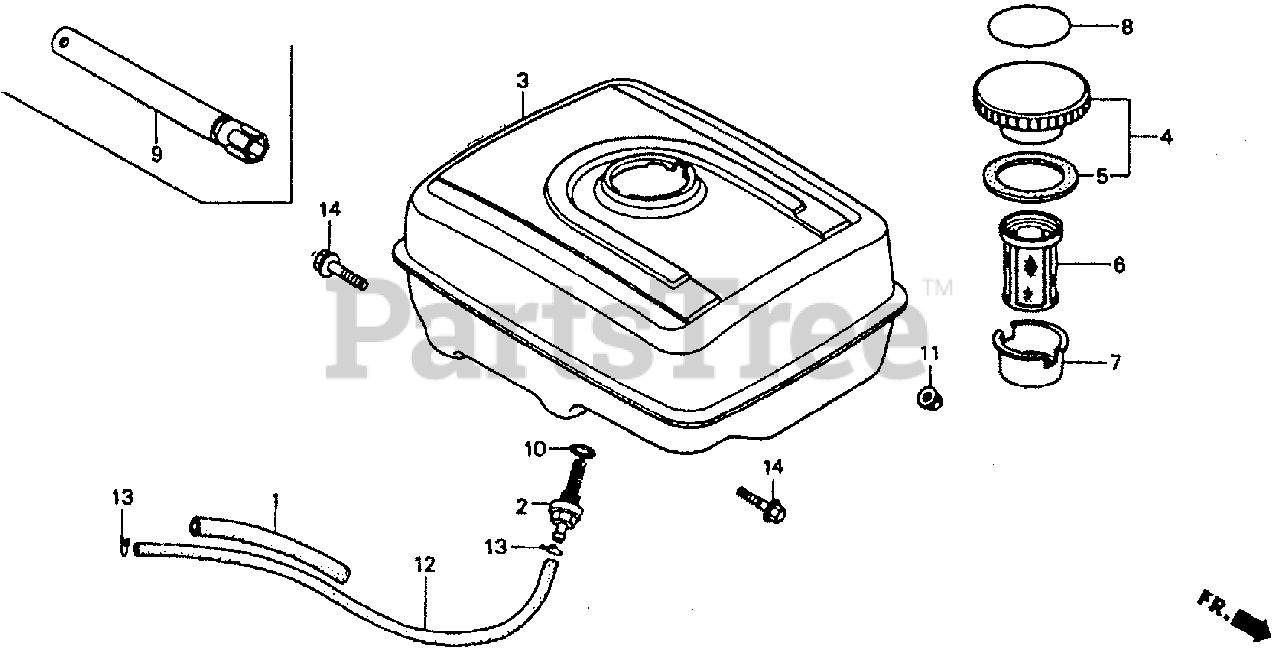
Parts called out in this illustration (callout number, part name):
1	RUBBER, SUPPORTER (107MM)
2	JOINT, FUEL TANK
3	TANK, FUEL *NH31* (Honda Code 3690070). (MCKINLEY WHITE)
3	TANK, FUEL *NH31* (Honda Code 7627540). (MCKINLEY WHITE)
3	TANK, FUEL *NH31* (Honda Code 8157174). (MCKINLEY WHITE)
4	CAP, FUEL FILLER
5	GASKET, FUEL FILLER CAP
6	FILTER, FUEL
7	HOLDER, FUEL FILTER
8	MARK, CAUTION (EXTERNAL)
9	WRENCH, SPARK PLUG
10	O-RING (13.5X1.5) (ARAI)
11	NUT, FLANGE (8MM)
12	BULK HOSE, FUEL (4.5X3000) (Honda Code 5137104). (4.5X222)
13	CLIP, TUBE (B8)
14	BOLT, FLANGE (8X25)
